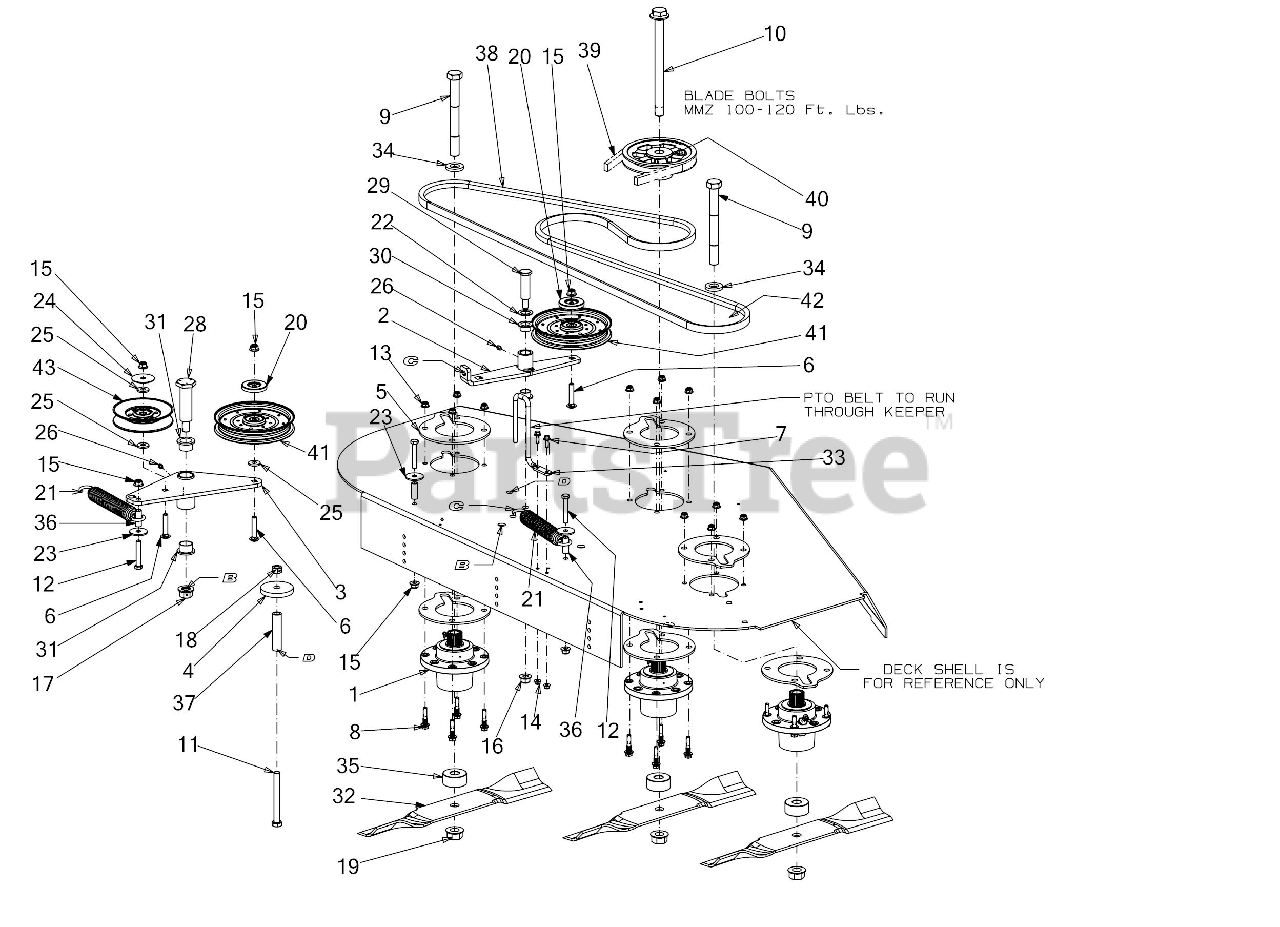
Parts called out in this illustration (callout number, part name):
1	SPINDLE ASSEMBLY
2	IDLER BRACKET
3	PTO IDLER ASSEMBLY
4	SPACER PLATE
6	CARRIAGE BOLT 3/8-16 x 2
7	SCREW 1/4-20 x .75 GR5
8	BOLT 5/16-18 x 1.50 GR5
9	SCREW 3/4-16 x 7.00 GR5
10	SCREW 3/4-16 x 9.00 GR5
11	SCREW 1/2-13 x 4.5 GR 5
12	SCREW 3/8-16 x 2.25 GR5
13	FLANGE LOCK NUT 5/16-18
14	FLANGE LOCK NUT
18	HEX NUT CTR LK 1/2-13
19	HEX FLANGE NUT 3/4
20	PULLEY CAP
21	SPRING 1.25" DIA X 8.5" LONG
22	FLAT WASHER .793ID x 1.24OD x .060
23	FLAT WASHER .406X1.500X.105
24	HUB CAP WASHER .406 x 1.92 x .060
25	FLAT WASHER .406ID X1.0 OD
26	GREASE FITTING
28	SHOULDER SCREW 1.0 x 3.15
29	SHOULDER SCREW
30	FLANGE BEARING
32	19" BLADE (HI LIFT)
33	ROD KEEPER
34	SPACER .812 ID x .218 LG
38	BELT-B SECTION x 119.45
39	V-BELT B SEC X 101.1
40	PULLEY-6.96 OD x .750 ID
41	IDLER PULLEY
42	SPINDLE PULLEY 6"
43	IDLER PULLEY 5.06 OD
